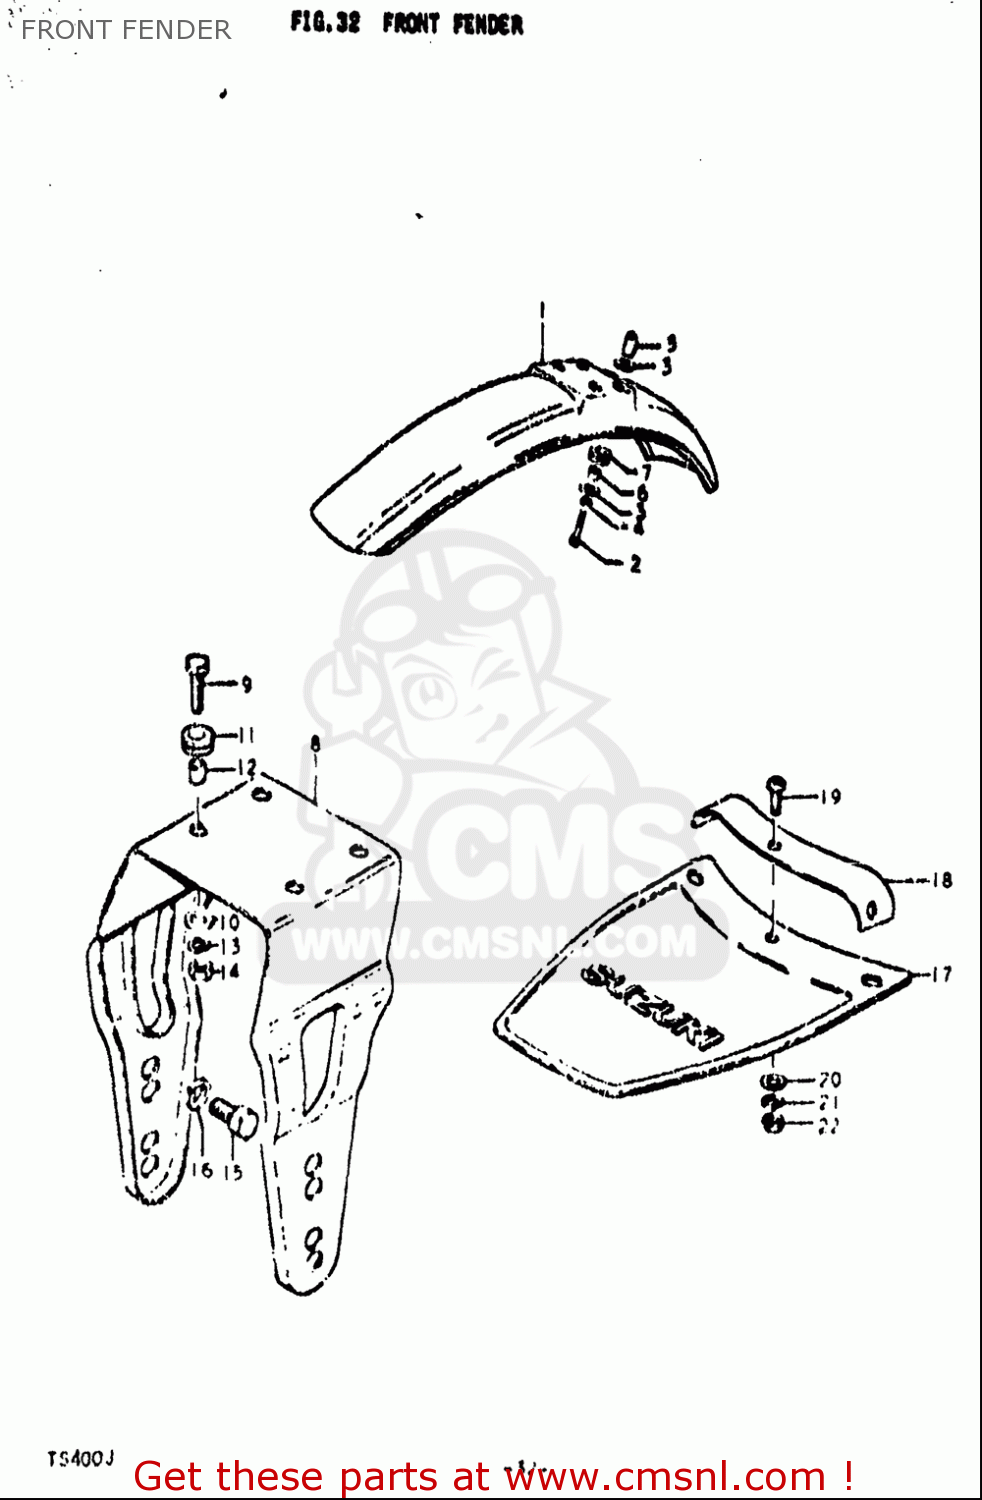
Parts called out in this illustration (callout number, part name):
2	BOLT
3	WASHER(6.5X24X1.2)
4	WASHER,LOCK
6	SPACER(6.5X10X13.5)
7	CUSHION
9	BOLT
10	WASHER(6.5X20X1.2)
11	CUSHION
12	SPACER(6.1X9X7.5)
13	WASHER,LOCK
14	NUT
15	BOLT
16	WASHER,LOCK
17	MUD FLAP,FRONT FENDER
19	SCREW
20	WASHER
21	WASHER,LOCK
22	NUT
